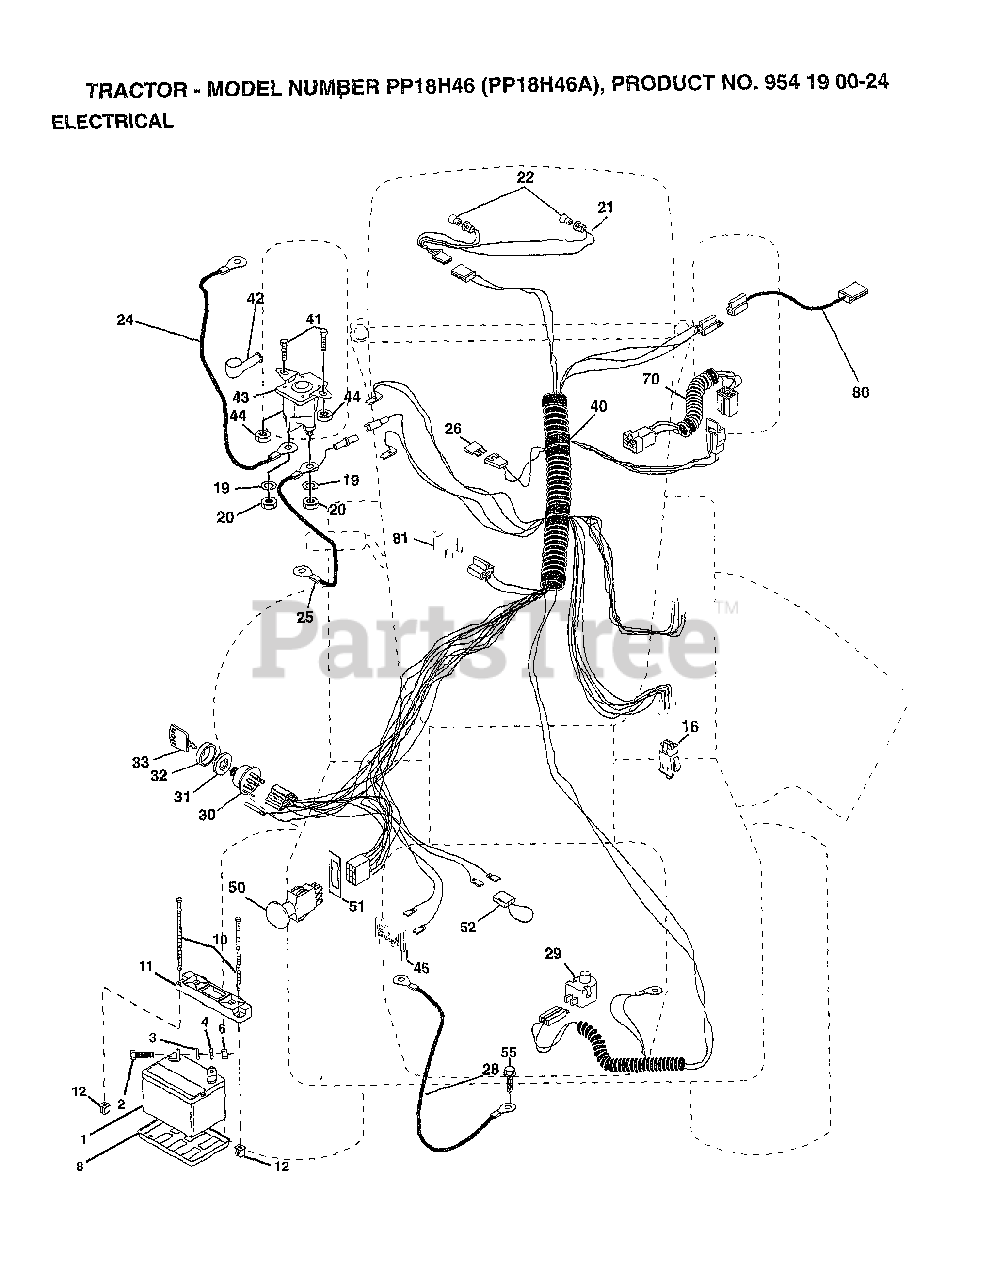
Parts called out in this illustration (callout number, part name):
3	WASHER
4	LOCKWASHER
8	"TRAY T, BATTERY"
11	HOLDDOWN BATTERY
16	SWITCH INTERLOCK
20	NUT
21	"HARNESS,LIGHT SOC"
22	HEADLAMP BULB
24	"CABLE T, BATTERY"
25	CABLE.6GA.22W/16W
26	FUSE HYT
28	CABLE.GRND.6GA.21
29	SWITCH.PLUNGER
30	SWITCH IGN 4POS
31	NUT IGNITION
32	COVER KEY SWITCH
33	KEY
40	IGNITION HARNESS
41	BOLT HXHD FIN
44	NUT HXKEP 1/4X20
45	AMMETER
50	PTO SWITCH.BLK
51	RING RETAIN PTO
52	PROTECTION LOOP
70	HARNESS.ENG.
80	HARNESS.CLUT.EVX.
